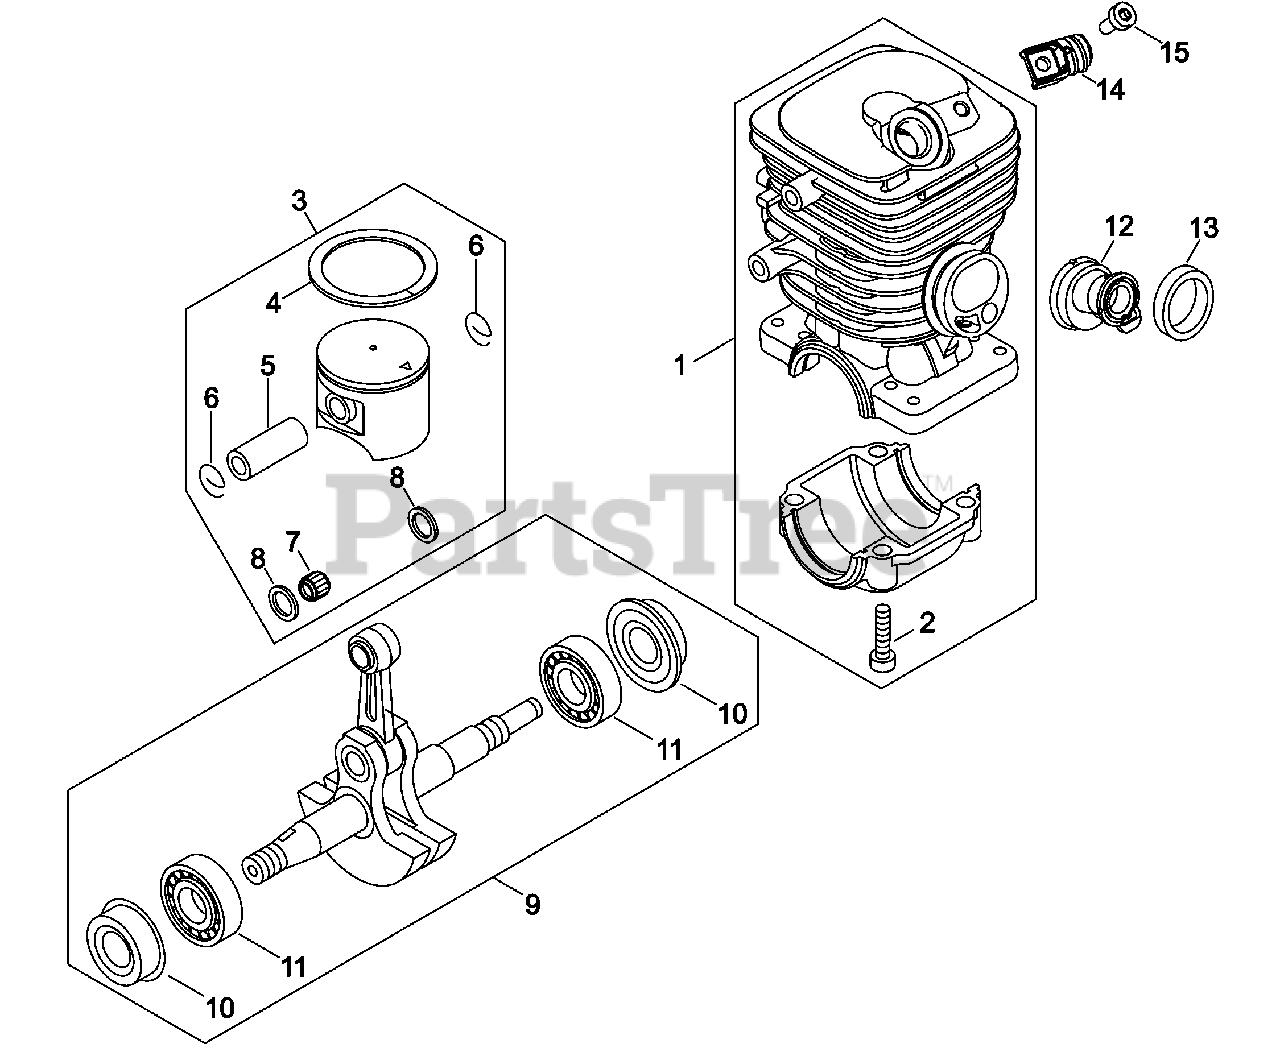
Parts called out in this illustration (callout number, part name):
1	CRANKCASE KIT
2	BOLT, TORX 5×25
3	PISTON KIT
4	RING, PISTON
5	PIN, PISTON 5.5×8×29
6	RING, SNAP
7	BEARING, NEEDLE 8
8	WASHER, THRUST
9	CRANKSHAFT ASSY
10	SEAL, OIL 12
11	BEARING, BALL 6201
12	BELLOWS, INTAKE
13	RETAINER, BELLOWS
14	HOLDER, SPRING
15	BOLT, TORX 5×12
